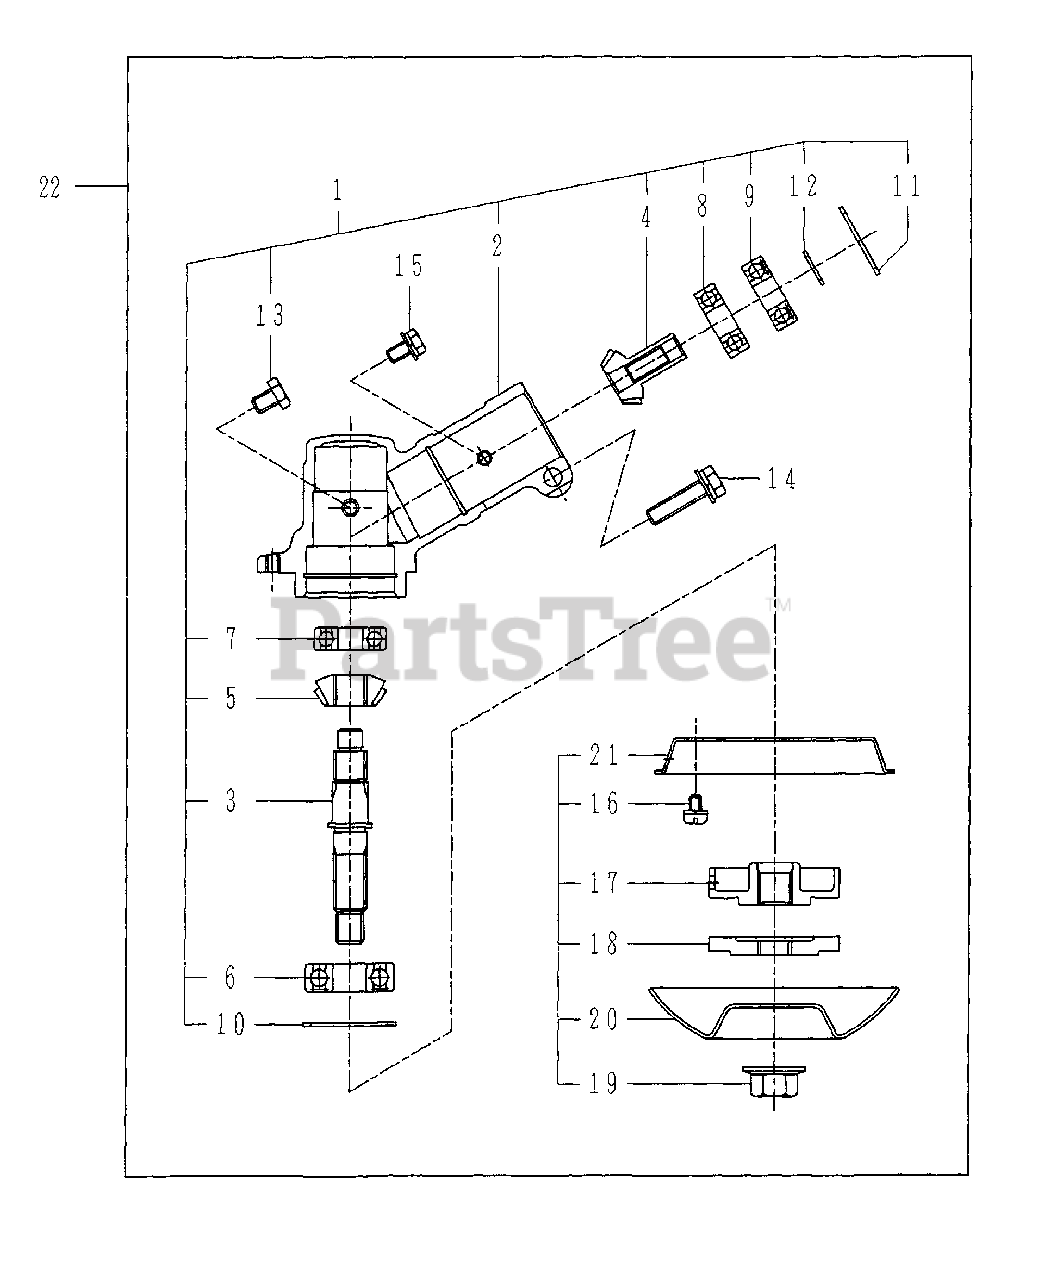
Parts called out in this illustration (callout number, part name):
1	GEAR CASE ASSY
2	CASE, GEAR
3	GEAR - SHAFT
4	GEAR - BEVEL
5	GEAR - BEVEL
6	BEARING, BALL
7	BEARING, BALL
8	BEARING, BALL
9	BEARING, BALL
10	RING, RETAINING
11	RING, RETAINING
12	RING, RETAINING
13	BOLT
14	BOLT
15	BOLT
16	BOLT
17	ADAPTOR, BLADE - UPPER
18	ADAPTOR, BLADE - LOWER
20	GUARD
21	SHIELD, DEBRIS
22	GEAR CASE ASSY
